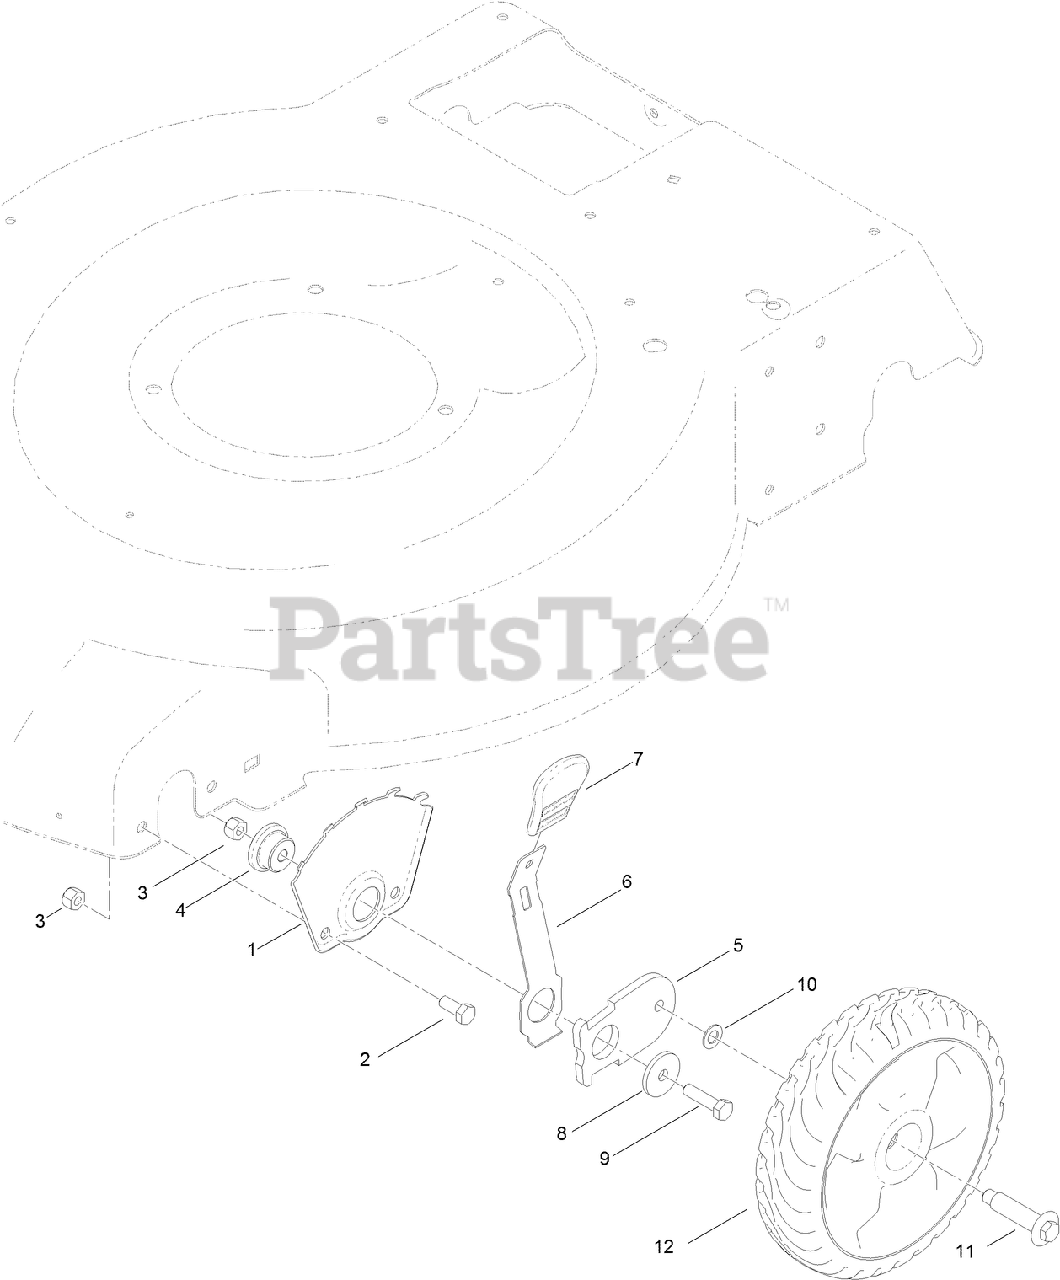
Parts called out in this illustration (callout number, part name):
1	PLATE-HOC, FRONT
2	SCREW-HH
3	NUT-LOCK, NI
4	BUSHING-MOUNT, HOC
6	ARM-SPRING
7	KNOB-HOC
8	WASHER-FLAT
9	SCREW-HH
10	WASHER
11	BOLT-SHOULDER
